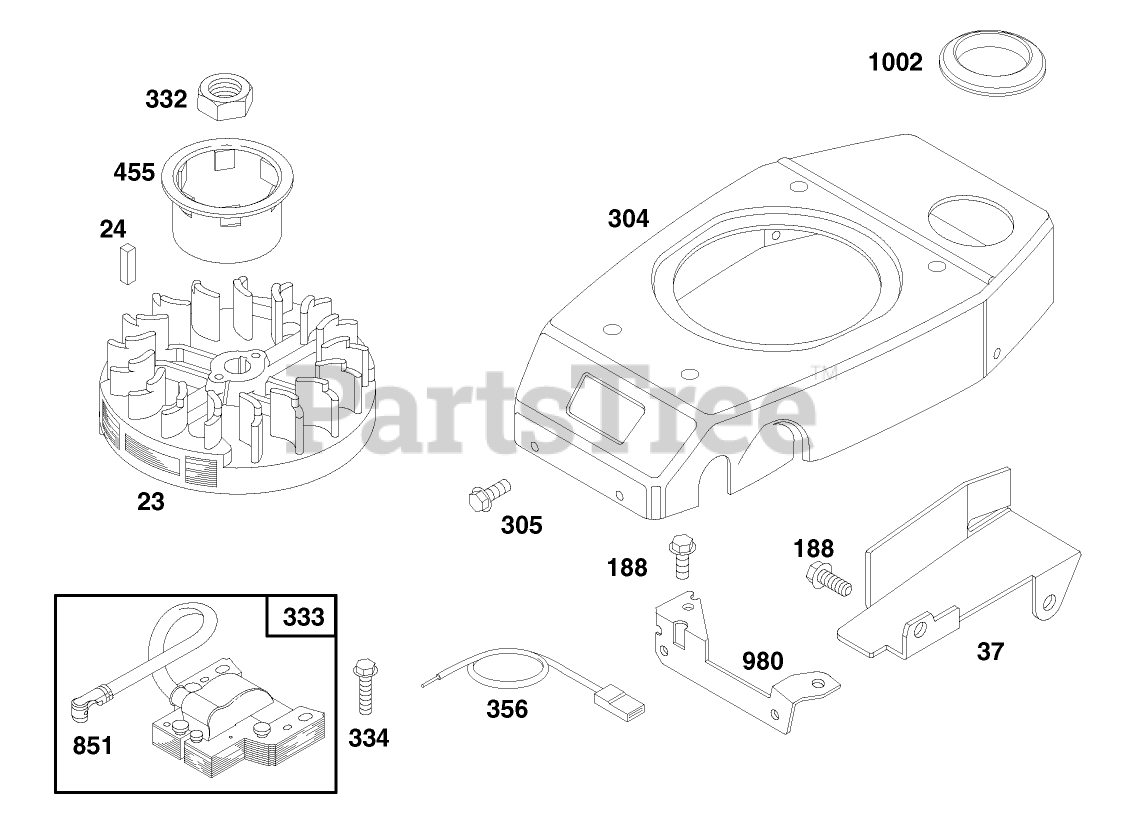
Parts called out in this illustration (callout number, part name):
24	KEY - FLYWHEEL
37	GUARD - FLYWHEEL
304	HOUSING - BLOWER
305	SCREW - HEX HEAD
332	NUT - HEXAGON
356	WIRE - GROUND
980	BRACKET-BLOWER HSG
